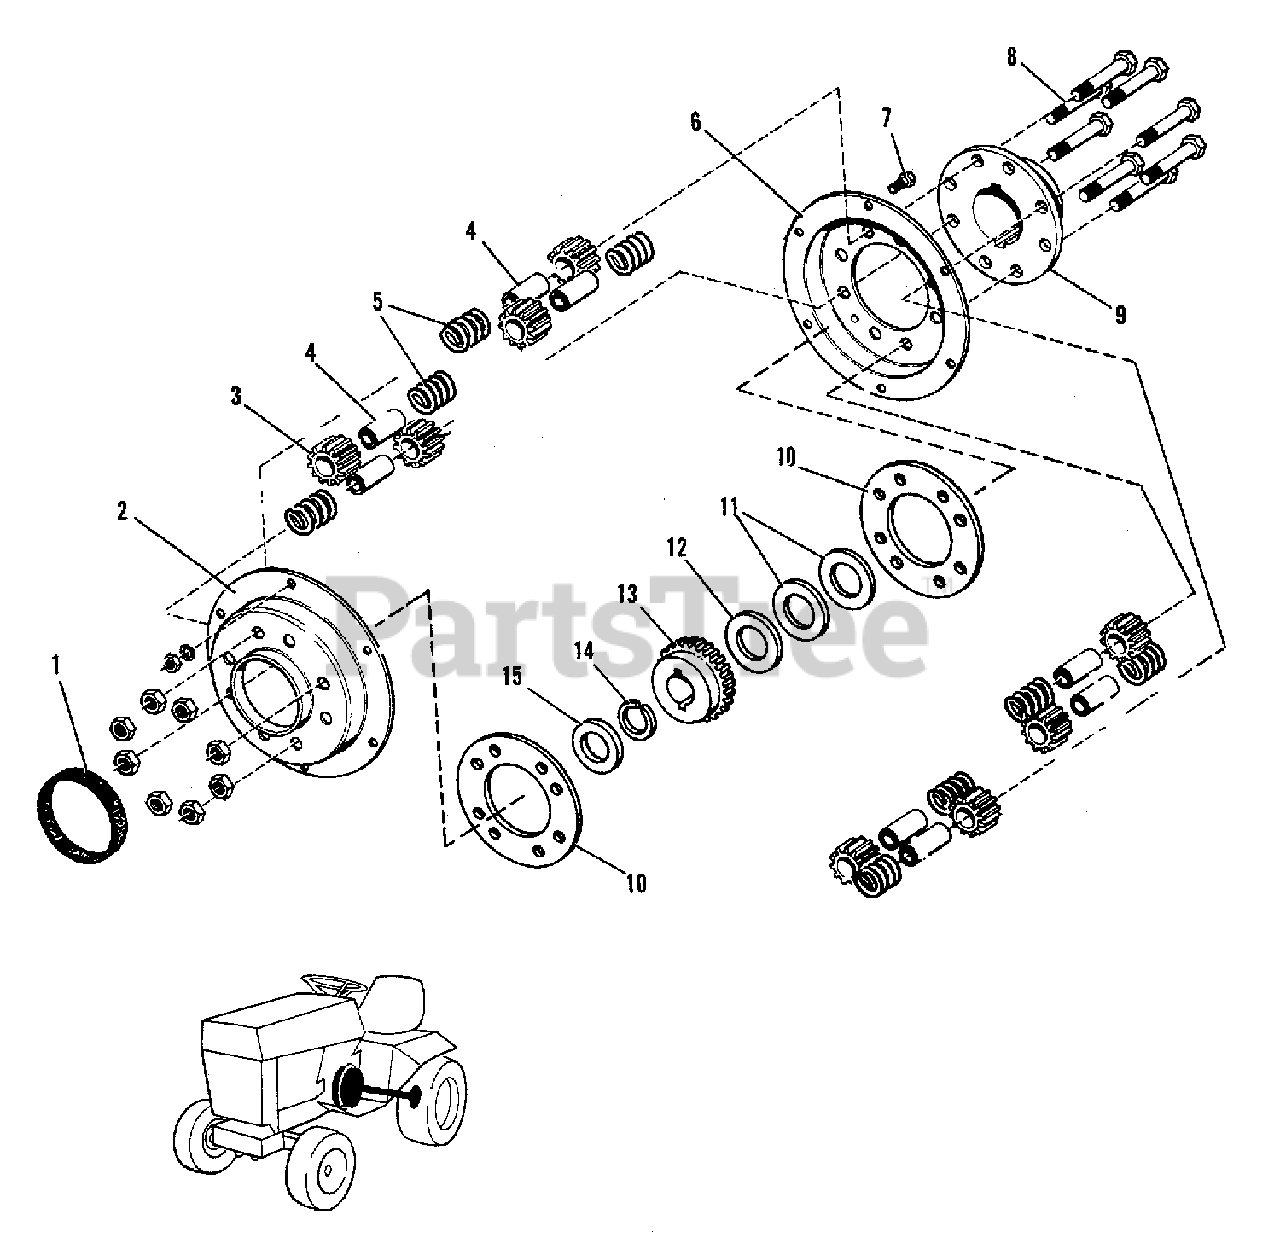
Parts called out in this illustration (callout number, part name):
1	SEAL, Cover
7	CAPSCREW, 1/4NC x 5/8
7	LOCKWASHER, 1/4
7	NUT, 1/4NC
8	CAPSCREW, 3/8NC x 2-1/2
8	NUT, 3/8NC, Lock
10	RING, Spacer
11	WASHER, Axle
12	WASHER, Axle
14	RING, Retaining
15	WASHER, Axle
